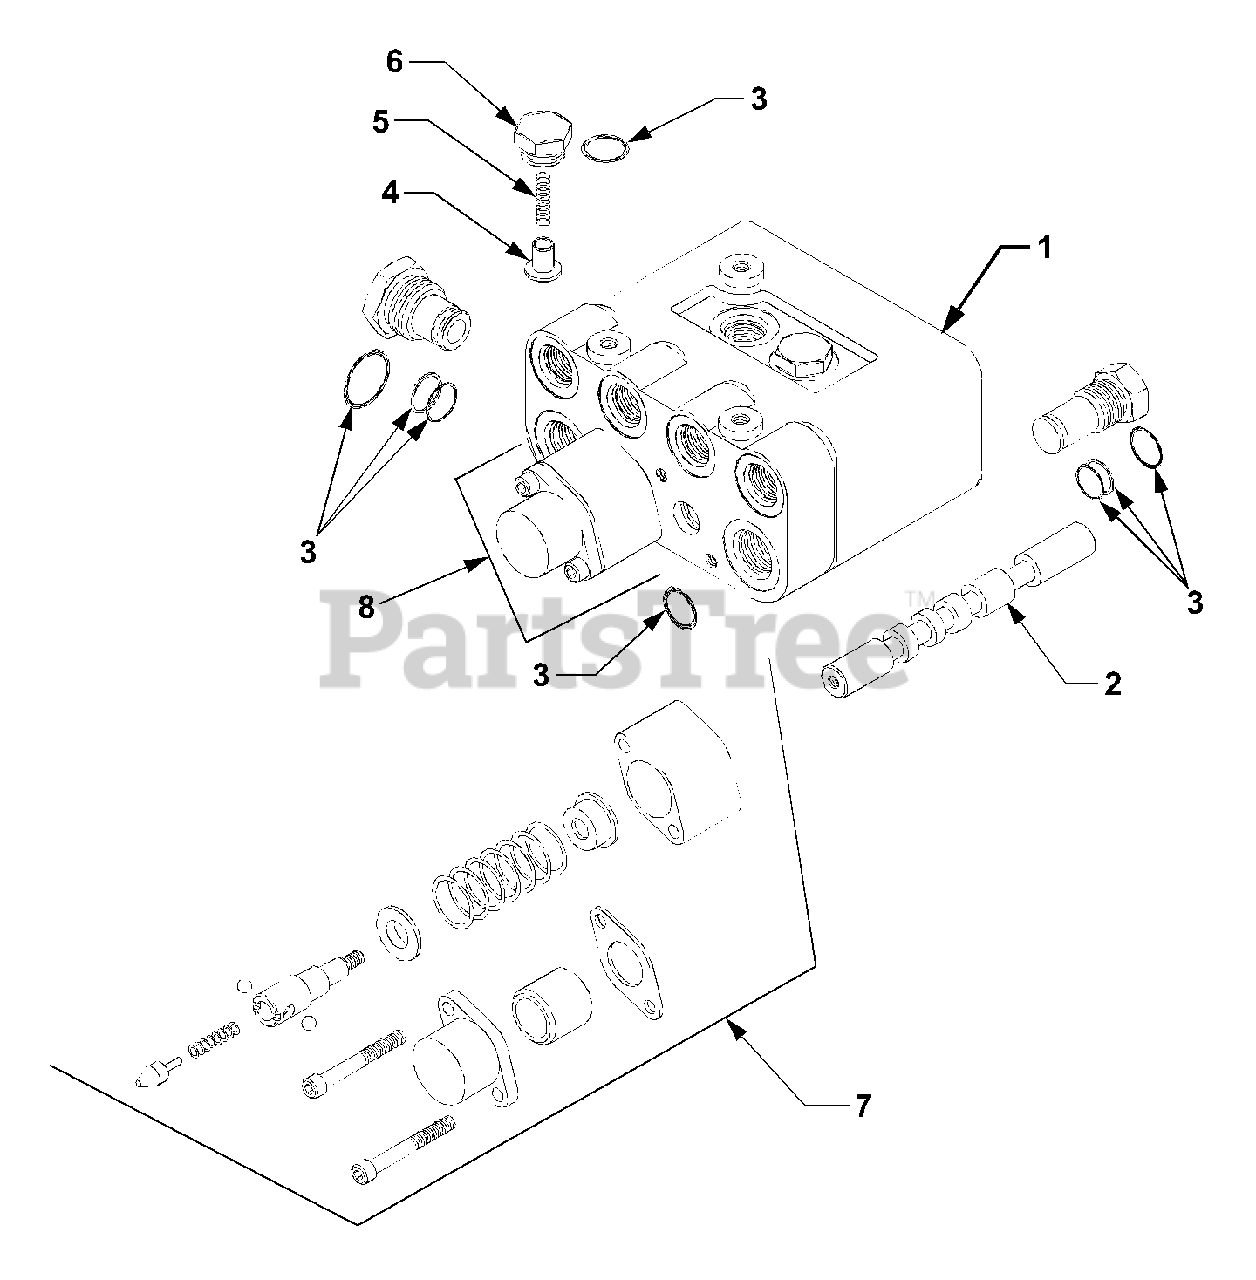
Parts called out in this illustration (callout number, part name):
1	Valve Body
2	Spool
4	Load Check Poppet
5	Load Check Spring
6	Load Check Plug
7	Float Detent Spool Repair Kit
8	Regen Spool Repair Kit
